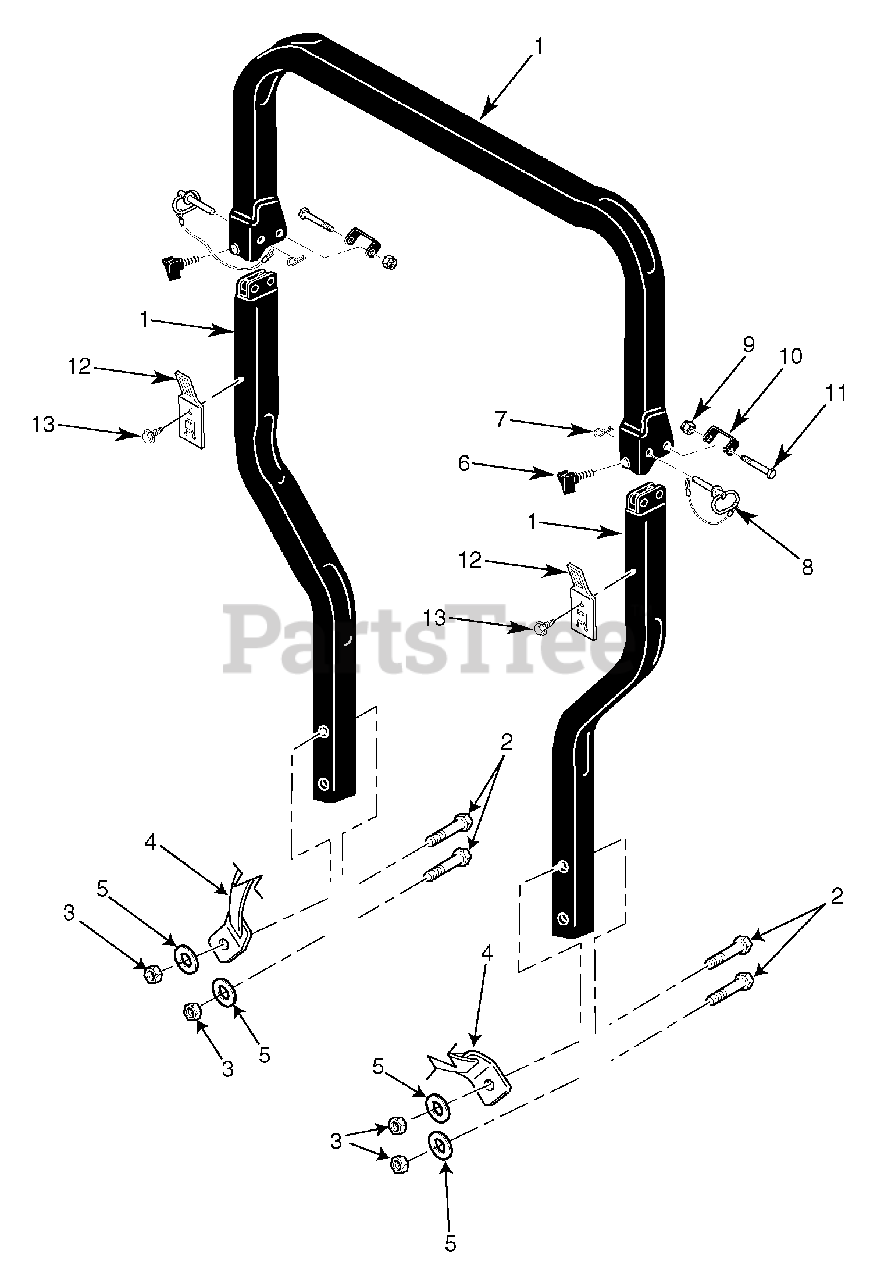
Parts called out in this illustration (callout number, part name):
1	STC Foldable ROPS Accessory
2	Bolt, Hex Head 1/2-13 x 3-1/2"
3	Nut, Center Lock 1/2-13
4	Seat Belt
5	Flatwasher, 1/2-.562 x 1.375 x .109
6	Thumb Screw, 5/16-18 NC x 3-4"
7	Hair Pin, Cotter
8	Pin
9	Nut, Center Lock 1/2-13
10	Bracket, Stop
11	Bolt, Hex Head 1/2-13 x 3-1/2"
12	Bracket, Seat Belt Hanger
13	Screw, 1/4-20 x 3/4"
